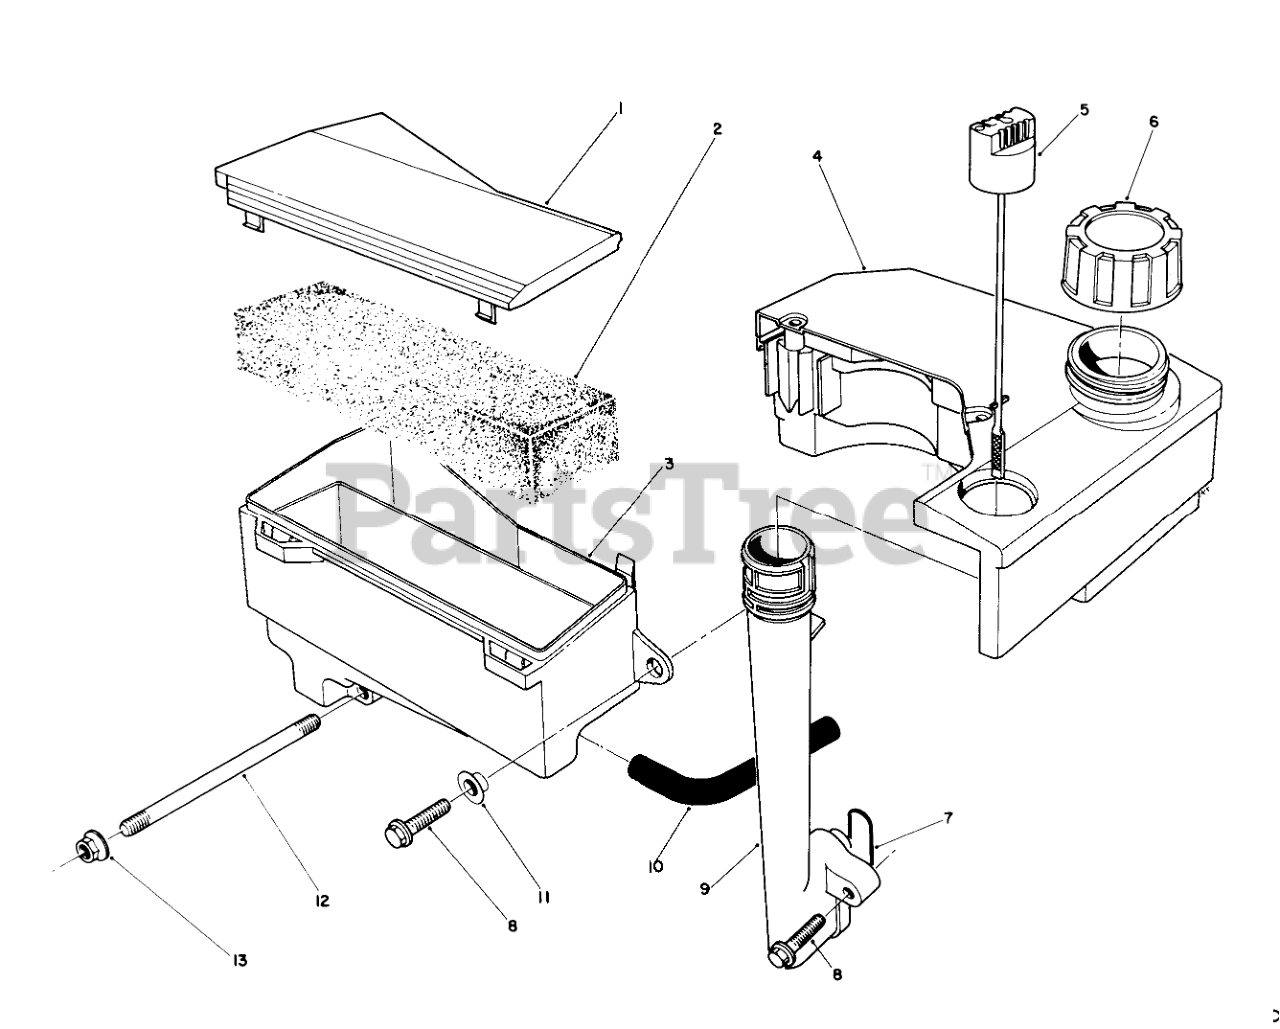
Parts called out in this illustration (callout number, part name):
1	AIR CLEANER CAP
3	Body-Air Cleaner
4	TANK ASM
5	Dipstick
6	GAS CAP ASM
7	O-RING
11	SPACER
12	Stud-Carburetor
